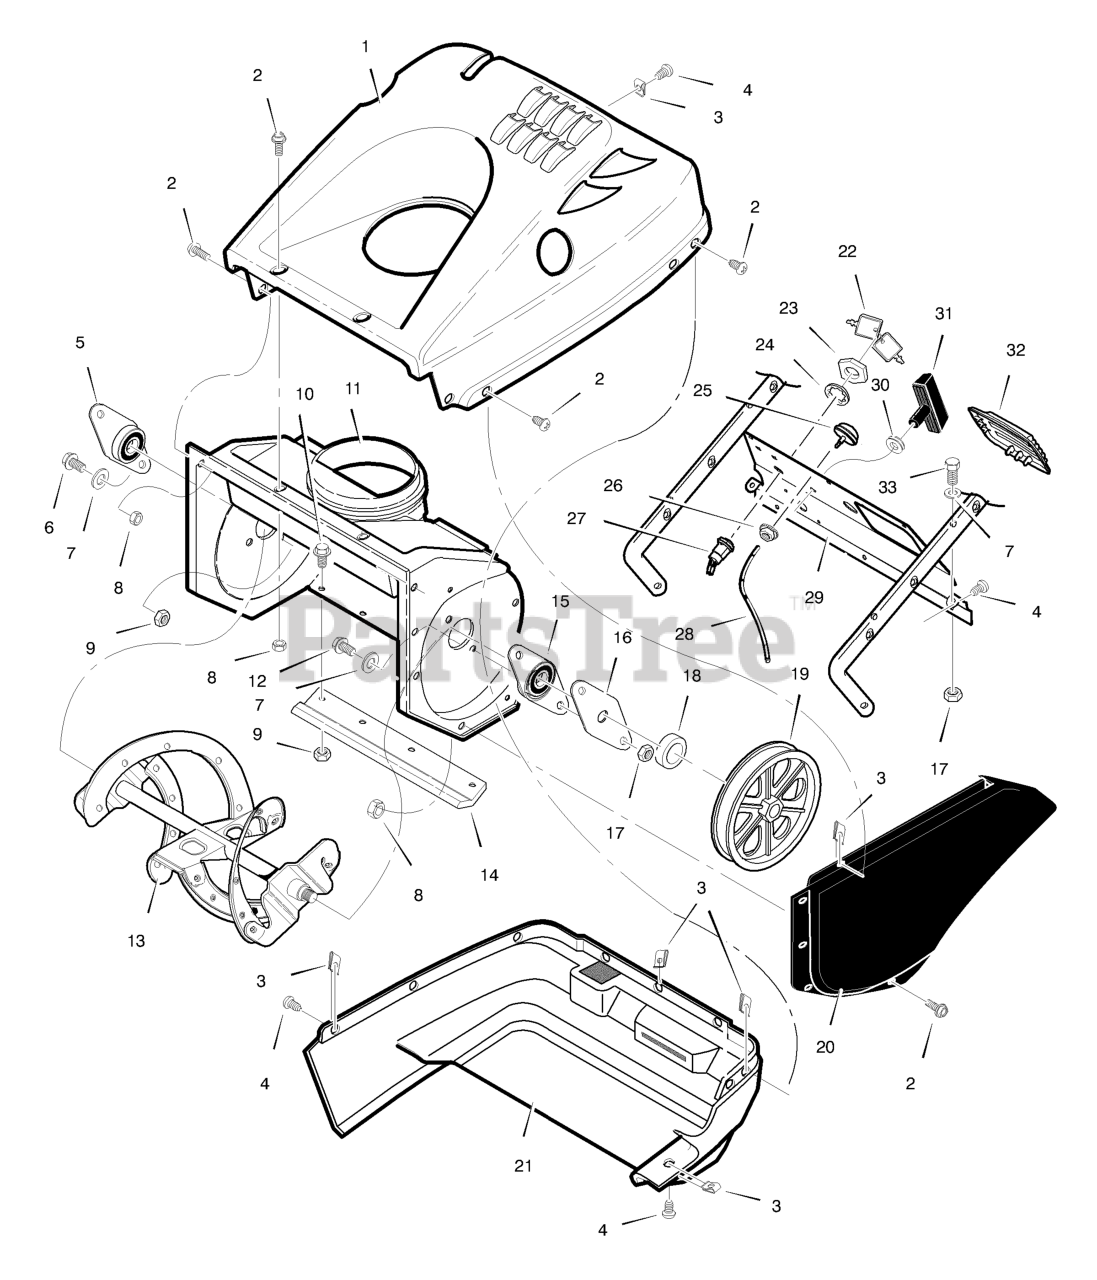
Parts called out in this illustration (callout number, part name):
1	COVER, TOP
2	SCREW, #10-24 x 0.50
3	NUT, 1/4-10 SPEED J-TYPE
4	SCREW, 1/4-14 x 0.75
5	FLANGE BEARING
6	SCREW, 1/4-20 x 1.00
7	WASHER, FLAT
8	NUT, #10-24 REGHEX CTRLK
9	NUT, 1/4-20 REGHEX CTRLK
10	SCREW, 1/4-20 x 0.75
11	AUGRT HOUSING ASSY.
12	SCREW, 1/4-20 x 0.63
13	AUGER ASSY., COMP.
14	BLADE, SCRAPER
15	SF BEARING & PLATE ASSY.
16	LT PLATE, RETAIKNER BRNG
17	NUT, 1/4-20 REXHEX CTRLK
18	SPACER, SLEEVE
20	COVER, BELT
21	COVER, BOTTOM
22	2 KEYS & RING ASSY.
23	NUT, 5/8-32
24	WASHER
25	BULB, PRIMER
26	NUT, 1/-20 REGHEX KEPS
27	SWITCH, IGNITION 45 DEG.
28	HOSE, PRIMER 9.5"
29	PANEL, CONTROL
30	GROMMET & WASHER
31	GRIP, RECOIL START
32	PANEL, ACCESS SPARK PLG
33	SCREW, 1/4-20 x 1.25
